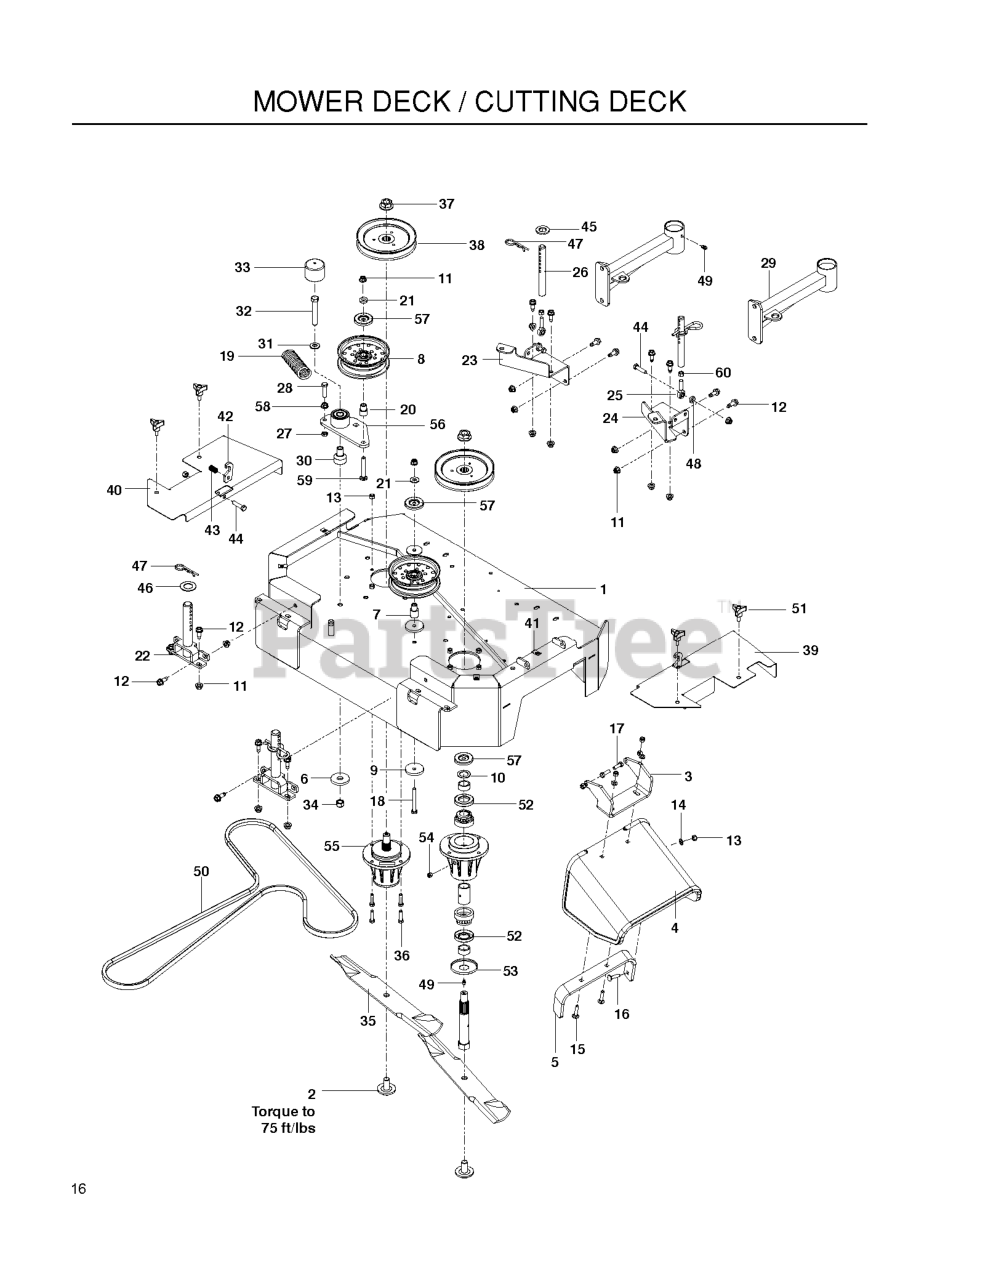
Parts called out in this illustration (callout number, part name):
1	CUTTER DECK 36" W/DECALS
2	BLADE BOLT/WASHER
3	HINGE CHUTE - BLACK
4	CHUTE, RUBBER DISCHARGE WB
5	BRKT, REINF-CHUTE WB
6	WASHER, SUPPORT
7	IDLER BUSHING
8	IDLER PULLEY
9	SPINDLE WASHER
10	MACHINE BUSHING
11	NUT 3/8-16 HEX FLG NYLOC ZD
12	BOLT 3/8-16 X 1.0
13	NUT 5/16 NYLOC
14	FLAT WASHER 5/16 SAE
15	RHSNB 5/16-18 X 1-1/2 GR 5 ZD
16	BOLT, CARRIAGE 5/16X1-1/4
17	HCS 5/16C X 1
18	HCS 3/8C X 3
19	SPRING, EXT
20	BUSHING, IDLER
21	WASHER, 3/8 THICK
24	SUPPORT, FRONT RH OR
25	ROD END - 3/8-24 RH
27	NUT 3/8-16 HEX JAM
28	HCS 3/8-16 X 1-1/2
29	SUPPORT, CASTER 36 OR
30	PIVOT, BEARING
31	CONTACT BELLSPR 1/2
32	HCS 1/2C X 3 1/4
33	CAP, VINYL
34	NUT 1/2-13 HEX NYLOC ZD
35	BLADE OEM 18"
36	HCS 5/16C X 1 1/4
37	NUT FLANGE 3/4-16
38	PULLEY - 6.57
39	COVER, 36 RH GY
40	COVER, 36 LH GY
41	U-CLIP 5/16-18 NUT RETAINER
43	SPRING - COMPRESSION
44	HCS 3/8C X 1 1/2
45	WASHER 3/4 FLAT SAE ZD
48	WASHER 3/8 X 3/4 X .187 TK
50	V-BELT 109
51	KNOB W/STUD
52	SHAFT SEAL
53	BOTTOM DUST CAP
54	PLUG-VENTED
55	HOUSING ASM, 72
56	ARM-IDLER W/BRG
57	DUST SHIELD
58	NUT 3/8C WHIZ
59	RHSNB 3/8-16 X 2.75
